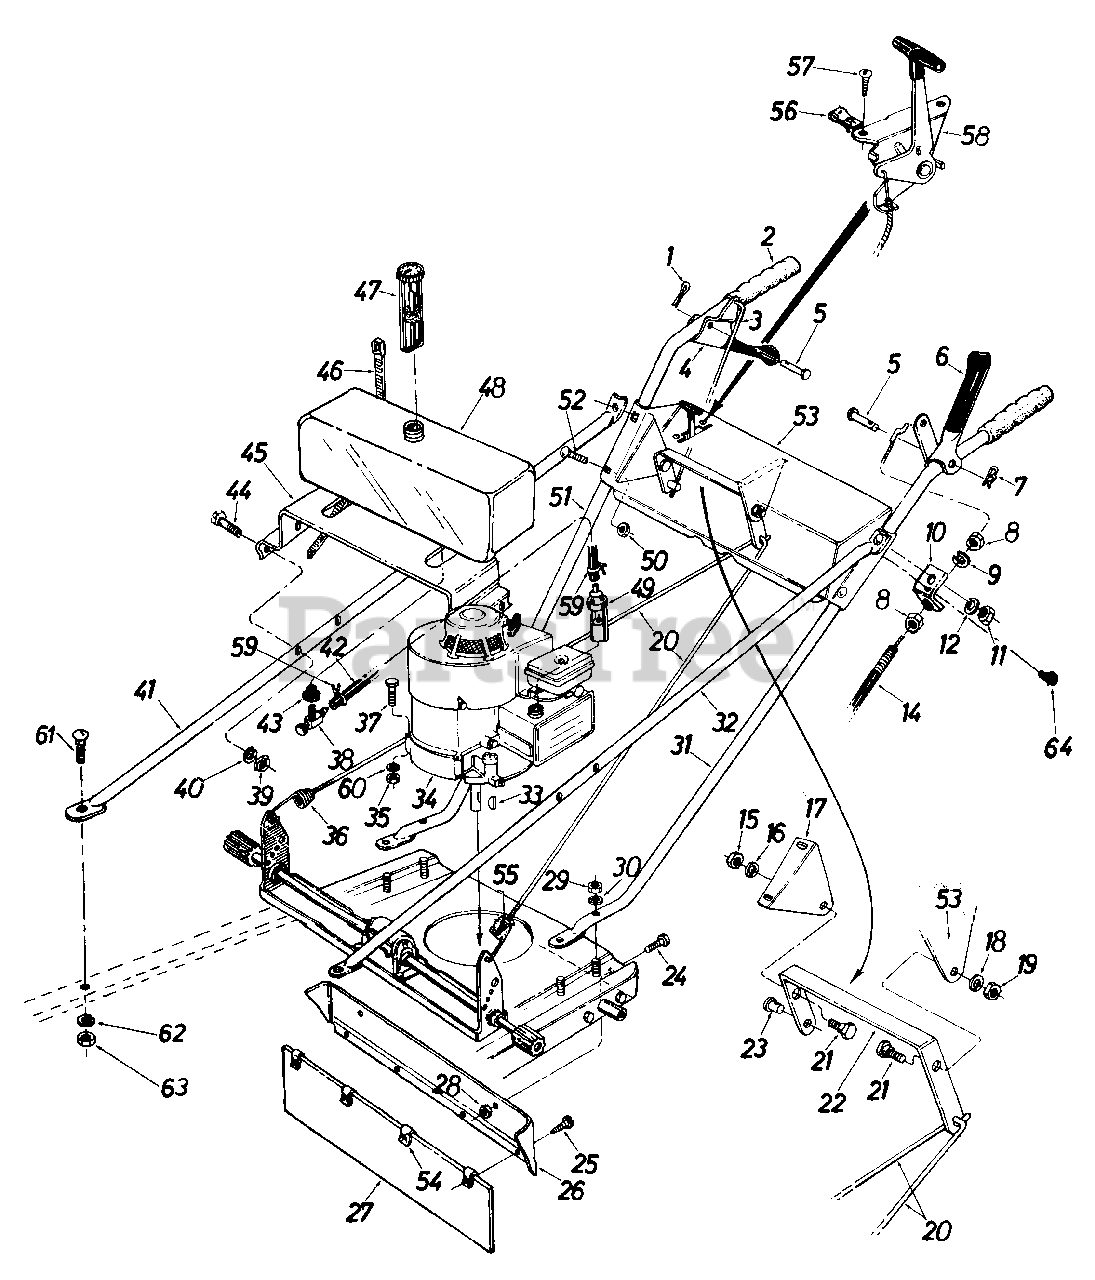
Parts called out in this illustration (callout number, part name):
1	Hairpin Cotter 5/16" Dia.
2	Grip
3	Clutch Rod
4	Clutch Grip
5	Clevis Pin .375 Dia. x 1.62 Lg
6	Blade Clutch Grip Ass'y. - R.H.
7	Cotter Pin 1/8 Dia. x 1.00" Lg
8	Hex Nut 5/16-18
9	L-Wash. 5/16" I.D.
10	Clutch Cable Bracket
11	Hex Nut 5/16-18
12	L-Wash. 5/16" I.D.
14	Clutch Control Cable
15	Hex Nut 3/8-16 Thd.
16	L-Wash. 3/8" I.D.
17	Bracket
18	L-Wash. 3/8" I.D.
19	Hex Nut 3/8-16 Thd.
20	Lockout Rod
21	Shld. Bolt .500 Dia. x .294
22	Link Bracket
23	Adjustment Ferrule 1/4-20
24	Hex Bolt 1/4-28 x .62 Lg.
25	Hex 8-Tap Scr. #10 x .62 Lg.
26	Drag Shield Adapter
27	Drag Shield
28	Hex Nut 1/4-28 Thd.
29	Hex Nut 3/8-16 Thd.
30	L-Wash. 3/8" I.D.
31	Handle - L.H. (Chrome)
32	Strut Bar
33	#6 Hi-Pro Key 5/32 x 5/8 Dia.
34	Engine
35	Hex Nut 5/16-24 Thd.
36	Extension Spring .96 O.D. x 2.12 Lg.
37	Hex Bolt 5/16-24 x 1.25" Lg.
38	Fuel Shut Off Valve
39	Hex Nut 5/16-24 Thd.
40	L-Wash. 5/16" I.D.
41	Strut
42	Gas Hose - 12" Long
43	Gas Tank Bushing
44	Hex Bolt 5/16-24 x 1.25 Lg.
45	Gas Tank Mounting Brkt.
46	Cable Ties
47	Fuel Gauge
48	Fuel Tank
49	Fuel Control Valve
50	Hex Nut 5/16-18 Thd.
51	Handle - R.H. (Chrome)
52	Carriage Bolt 5/16-18 x 1.75 Lg.
53	Handle Panel Ass'y.
54	Speed Nut #102
55	Hex Ins. L-Nut 1/4-20 Thd.
56	Speed Nut #10 I.D.
57	Hex AB-Tap Scr. #10 x .50" Lg.
58	Throttle Control Ass'y. Comp.
59	Hose Clamp 3/8" I.D.
60	L-Wash. 5/16" I.D.
61	Carriage Bolt 5/16-18 x .62" Lg.
62	L-Wash. 5/16" I.D.
63	Hex Nut 5/16-18 Thd.
64	Hex Wash. Hd. Self-Tapping Scr. 1/4-20 x .50" Lg.
